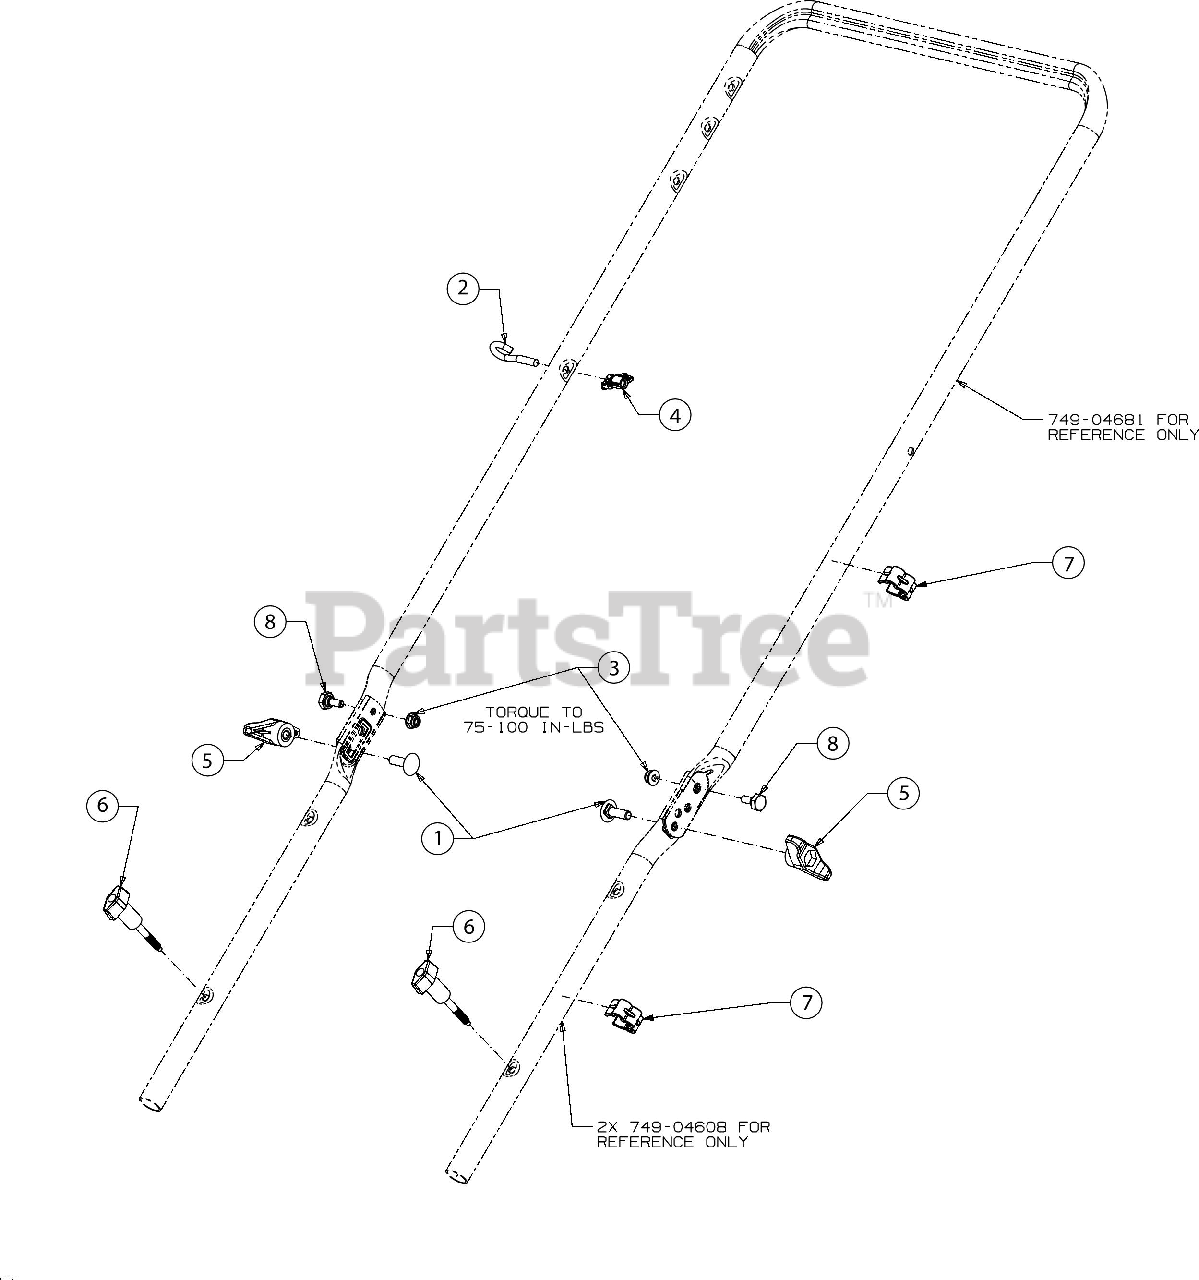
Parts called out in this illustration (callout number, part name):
1	SCREW 5/16-18 X 1.00 GR5
2	EYEBOLT 1/4-20
3	FLANGE LOCK NUT
4	HANDLE KNOB
5	WING KNOB 5/16-18
6	WING KNOB 1/4-20
7	CONDUIT CLIP
8	SHOULDER SCREW
